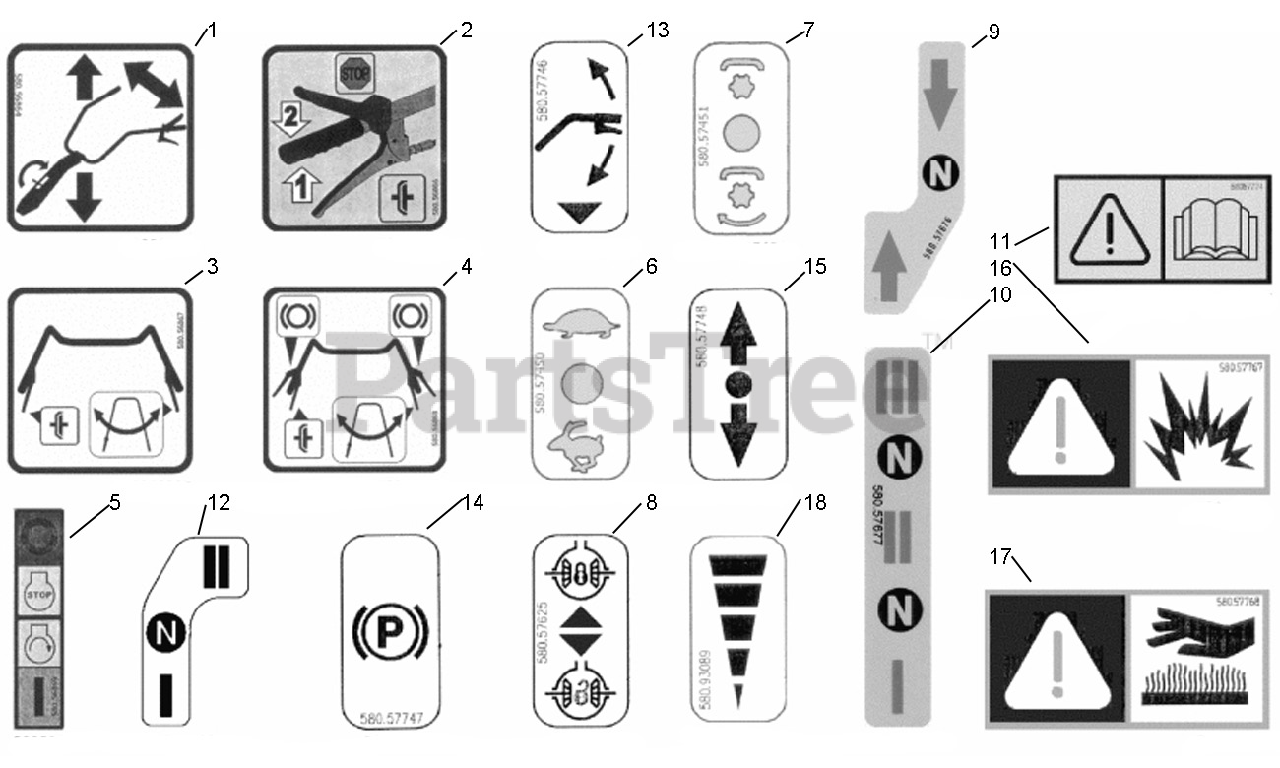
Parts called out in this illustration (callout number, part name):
1	DECAL
2	DECAL
3	DECAL
4	DECAL
5	DECAL
6	DECAL
7	DECAL
8	DECAL
9	DECAL
10	DECAL
11	DECAL
12	DECAL
13	DECAL
14	DECAL
15	DECAL
16	DECAL
17	DECAL
18	DECAL
